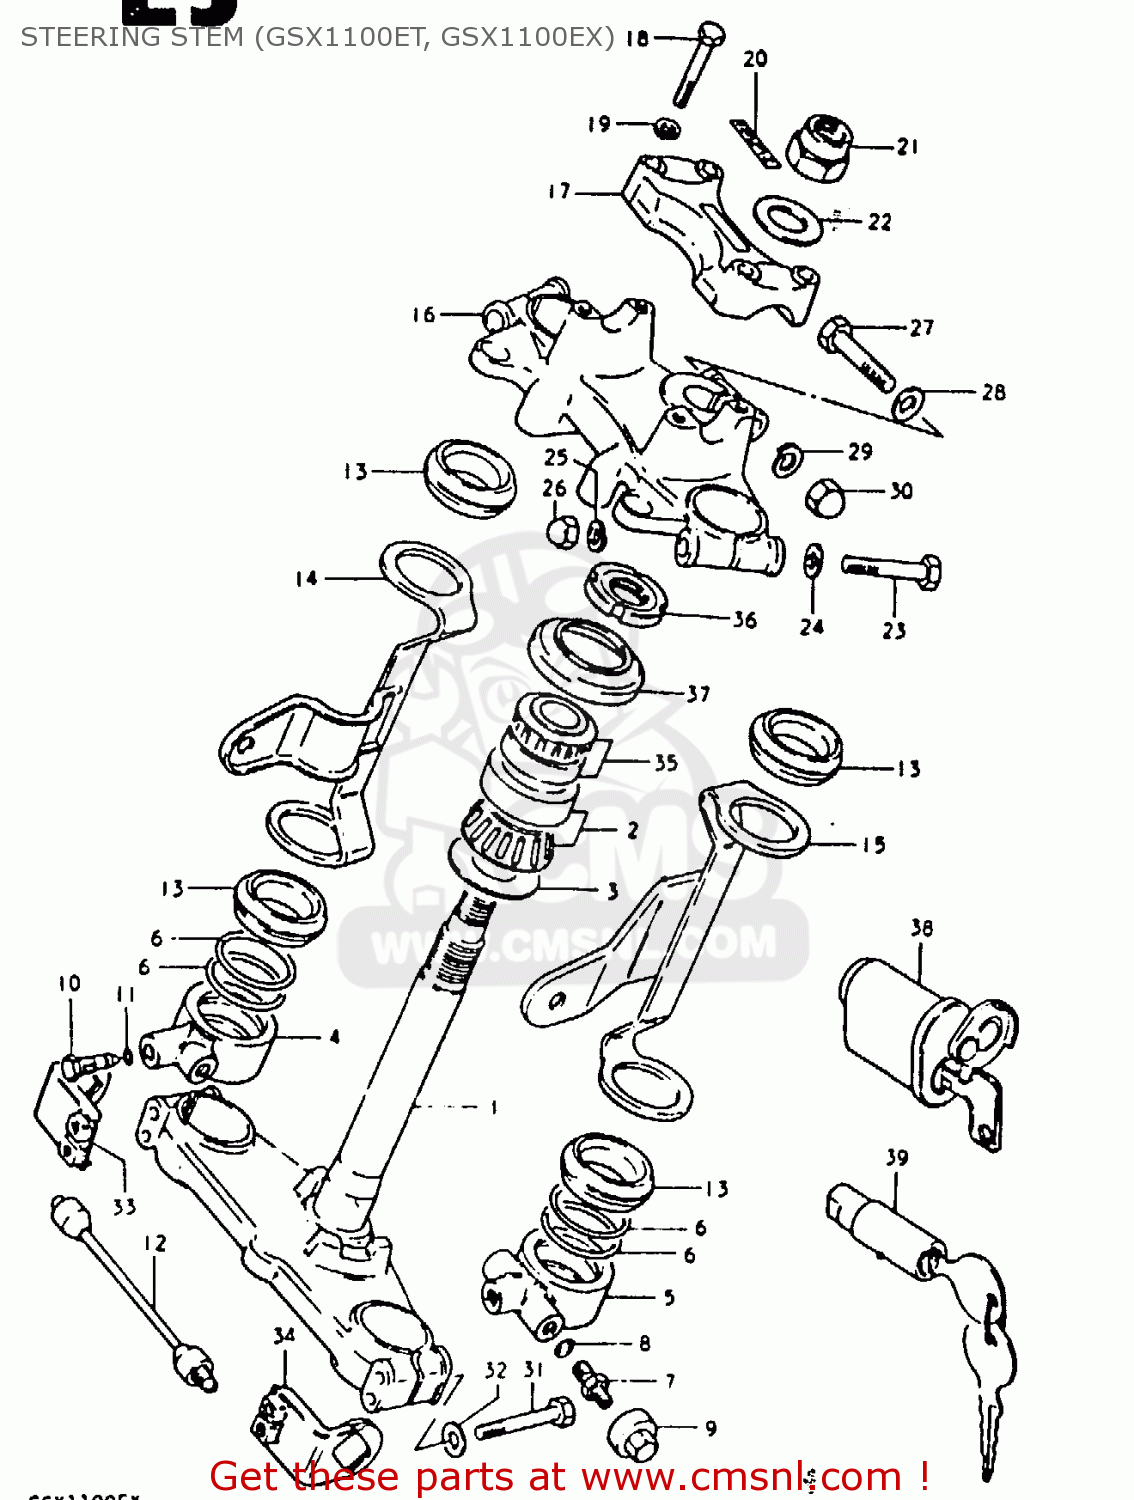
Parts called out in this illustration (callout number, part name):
1	STEM,STEERING
2	BEARING
3	WASHER,THRUST
4	JOINT,AIR,RIGHT
5	BRACKET,FORK CONNECTING
6	O RING
7	VALVE
8	O RING
9	CAP,VALVE
10	VALVE,STOP
11	O RING
12	HOSE
13	CUSHION,HEADLAMP BRACKET
14	BRACKET,HEAD L
15	BRACKET, HEAD LAMP LH
16	HEAD,STEERING STEM
17	HOLDER, HANDLE
18	BOLT
19	LOCK WASHER
20	EMBLEM,HANDLE CLAMP
21	NUT,FR FORK UPR BRACKET
22	WASHER
23	BOLT 10X55
24	WASHER
25	LOCK WASHER
26	NUT 10MM
27	BOLT 8X50
28	WASHER
29	WASHER,LOCK,8.
30	NUT,M8X1.25X12
31	BOLT 8X55
32	WASHER
33	BRACKET, TURN SIGNAL RH
34	BRACKET, TURN SIGNAL LH
35	TAPER,ROLLER BEARING
36	NUT,STEERING STEM(25X44X10)
37	DUST SEAL,STEERING,UPPER
